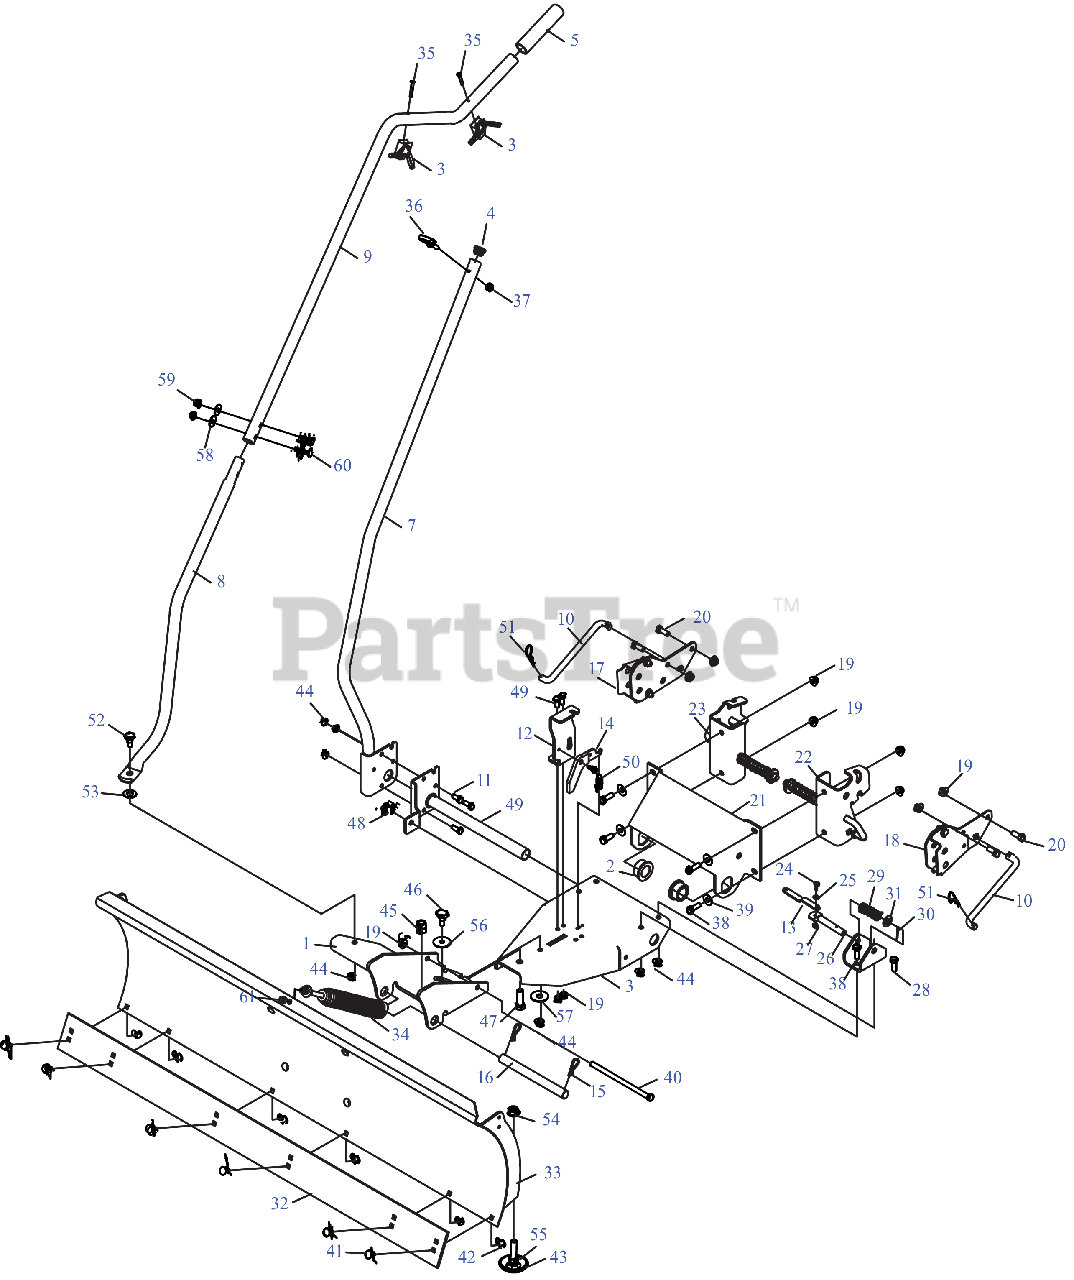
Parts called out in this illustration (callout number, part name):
2	FLANGE BEARING
3	BLADE RELEASE CABLE
10	SUPPORT ROD
11	WELDED SHAFT ASSEMBLY
13	LOCKING ASSEMBLY
15	COTTER PIN
16	PIVOT SHAFT
17	SCREW 5/16-18
17	FLANGE LOCK NUT 5/16-18
18	FLANGE LOCK NUT 5/16-18
18	SCREW 5/16-18
19	FLANGE LOCK NUT 5/16-18
20	SCREW 3/8-16 x .880 GR5
22	COTTER PIN-5/32 DIA
22	FLAT WASHER .531 x 1.25 x .181
22	J HOOK ARM ASSEMBLY
23	J HOOK ARM ASSEMBLY
23	COTTER PIN-5/32 DIA
23	FLAT WASHER .531 x 1.25 x .181
24	LOCKING ASSEMBLY
25	WASH, FLAT .480X.1
26	LIFT LOCK ROD
27	HEX NUT
28	LOCKING ASSEMBLY
29	COMPRESSION SPRING .772 OD x 1.95
30	COTTER PIN 3/32 x 1.25
31	FLAT WASHER .510X.995
34	TRIP SPRING KIT
35	SCREW #10-24 x 1.375
37	HEX FLANGE NUT
38	SCREW 3/8-16 x 1 GR5
39	WASHER-.395 x 1.0 x .62
40	SCREW 3/8-16 x 7.00 GR5
41	CARRIAGE BOLT 5/16-18 x .75
42	HEX NUT INS
45	HEX NUT CTR LK 1/2-13
46	SHOULDER SCREW
47	SCREW 1/2-13X1.50 GR5
48	SCREW 3/8-16 x 1
49	SCREW 5/16-18 x .75 GR5
50	EXTENSION SPRING
51	INTERNAL COTTER PIN
52	SHOULDER SCREW .498 DIA x .340
53	TEFLON WASHER .565X1.20
55	HEX JAM NUT 1/2-13
56	FLAT WASHER
57	FLAT WASHER .390 ID x 1.50 OD x .075
58	FLAT WASHER 344X1.00
59	HEX NUT 5/16-18
60	CARRIAGE BOLT 5/16-18 x 1.5
61	HEX NUT 3/8-16
62	SHOULDER SCREW
